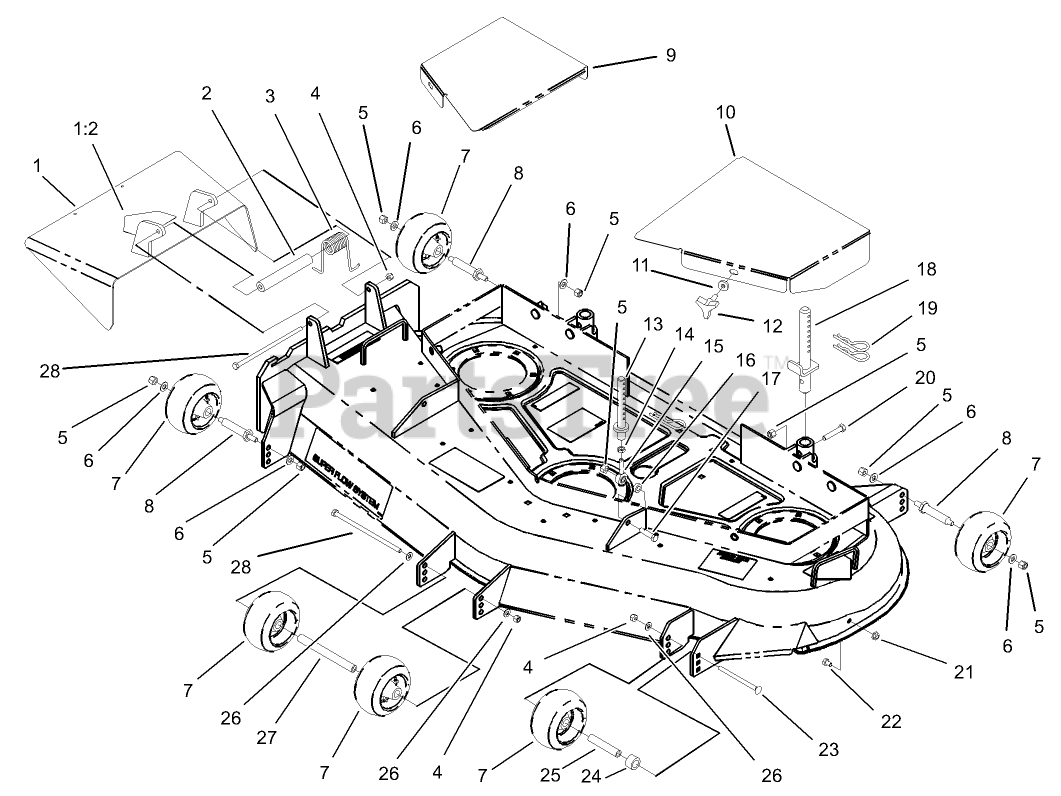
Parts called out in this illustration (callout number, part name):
1	Deflector ASM
1:2	DECAL-DANGER
2	SPACER
3	SPRING-TORSION
4	NUT-LOCK, NI
5	NUT-LOCK, NI
6	WASHER-FLAT
7	WHEEL-GAGE
8	SPACER
9	COVER-BELT, RH
10	COVER-BELT, LH
11	WASHER-RUBBER
13	FRONT PIN ASM
14	NUT-HJ
15	BALLJOINT
16	SPACER
17	SCREW-HH
18	REAR PIN ASM
19	PIN-HAIR
20	SCREW-HH
21	NUT-HF
22	SCREW-HH
23	SCREW-CARR
24	SPACER-WHEEL
25	BUSHING-ROLLER
26	WASHER-PLAIN
27	SPACER-WHEEL
28	SCREW-HH
